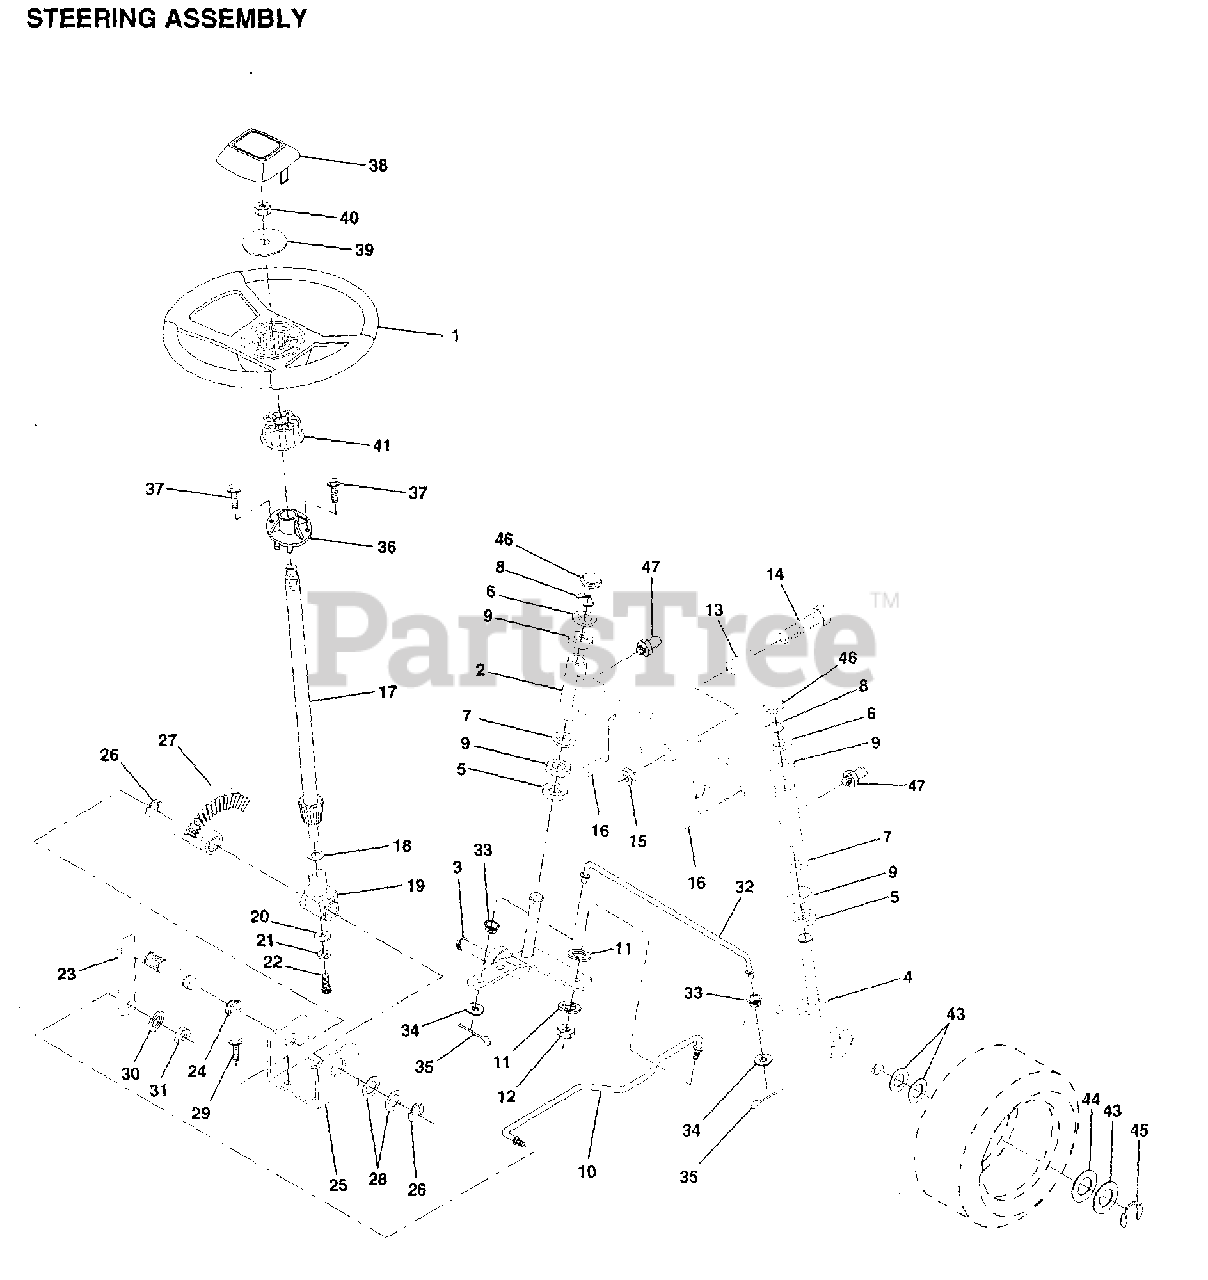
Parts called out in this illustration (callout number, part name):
3	SPINDLE LH
4	SPINDLE RH
5	WASHER .T
6	WASHER
7	WASHER
8	RING
9	COL. SRTG. BEAR.
11	LOCKWASHER
13	BEARING
14	BOLT HEX 5/8-11
15	"NUT-LOC,FLANGE LT"
16	AXLE PIN
17	STEERING SHAFT
18	THRUST WASHER
19	SUPPORT.SHAFT
21	LOCKWASHER
22	"SCREW,SPECIAL"
24	NYLINER T
25	"BRKT,STEERING"
26	RING
27	GEAR SECTOR
28	WASHER .T
29	SCREW
30	LOCKWASHER
32	TIE ROD
33	BUSHING.DRAGLINK
34	WASHER
35	COTTER PIN
38	ST WHL INSERT CAP
39	WASHER
41	ADAPTER LT
43	WASHER
44	WASHER
45	RING
46	CAP
47	ZERK M
